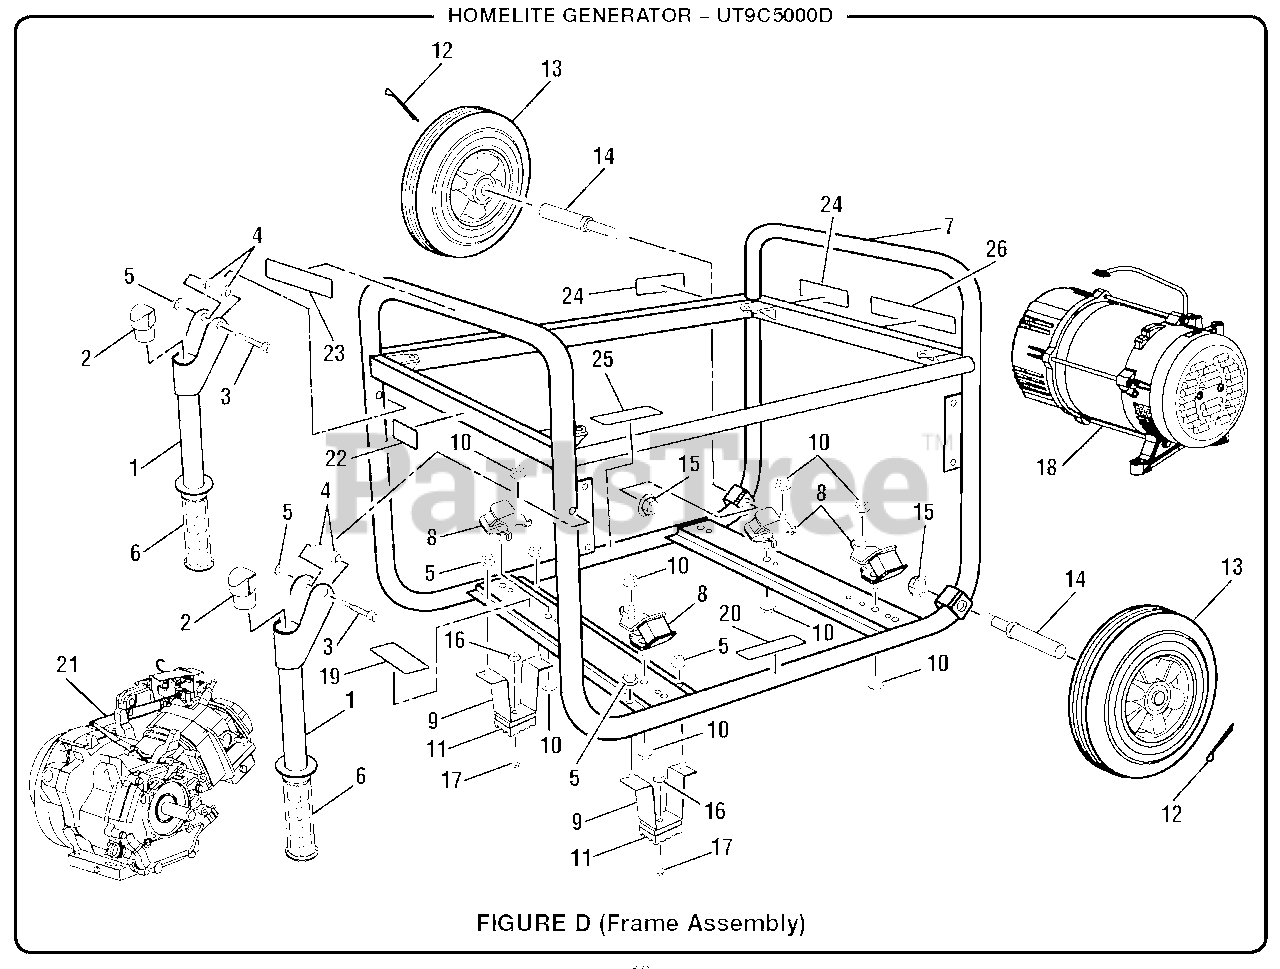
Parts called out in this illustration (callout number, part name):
1	Handle Bar Assembly
2	Handle Bar Plug
3	Bolt (M8 x 45 mm)
4	Handle Bar Insert
6	Handle Grip
8	Motor Mount
9	Foot Bracket
10	Nut (M10)
11	Rubber Foot
12	Cotter Pin (3 mm)
13	Wheel (10 in)
15	Nut (M12, Flange Hd)
16	Flange Nut (M6)
17	Screw (M6 x 25)
18	Generator Head Assembly
19	Data Label
20	Lubricant Label
21	Engine 420cc
22	Fuel Valve Label
23	Fire Danger Label
24	Hot Surface Warning Label
25	Combustion Label
26	Ground Warning Label
